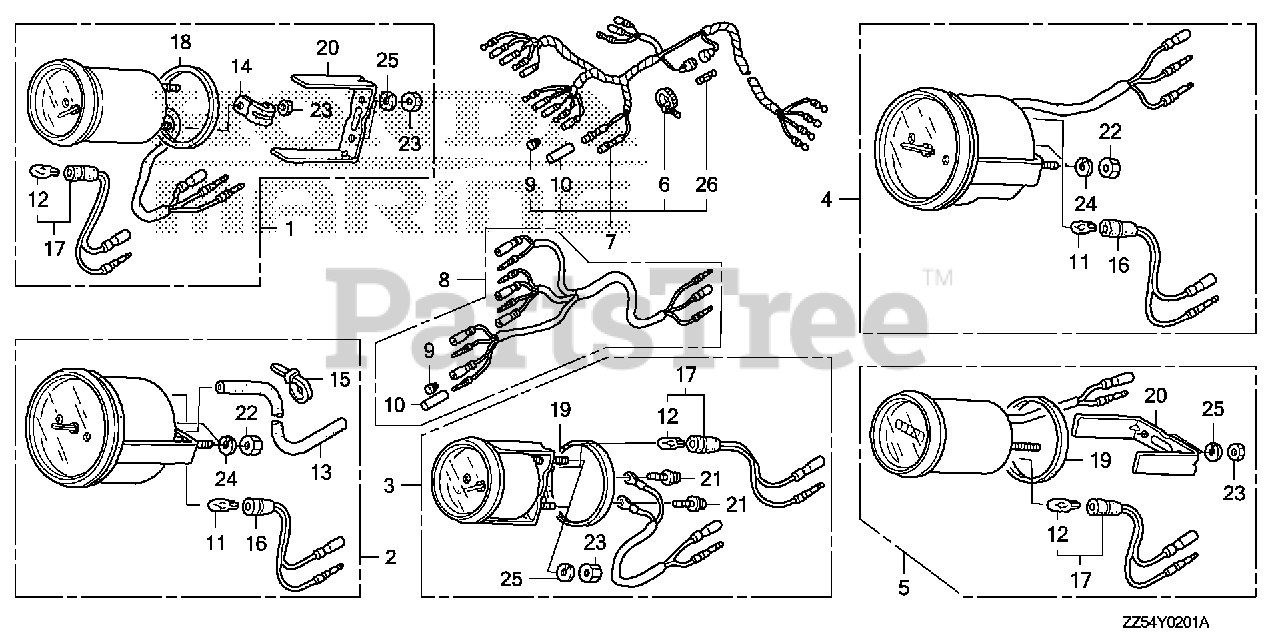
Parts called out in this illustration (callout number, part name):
4	METER KIT, TACHO
4	METER KIT, TACHO (B)
6	BAND B1, CABLE Use up to Frame SN 1001879.
7	HARNESS ASSY., METER (A)
9	PLUG, CONNECTOR (INNER) (TROLLING CONTROL)
10	PLUG, CONNECTOR (OUTER) (ENGINE NO.)
11	BULB, WEDGE BASE (T10) (12V 1.7W) (STANLEY)
16	SOCKET
22	NUT, HEX. (5MM)
24	WASHER, SPRING (5MM)
26	FUSE A (10A)
